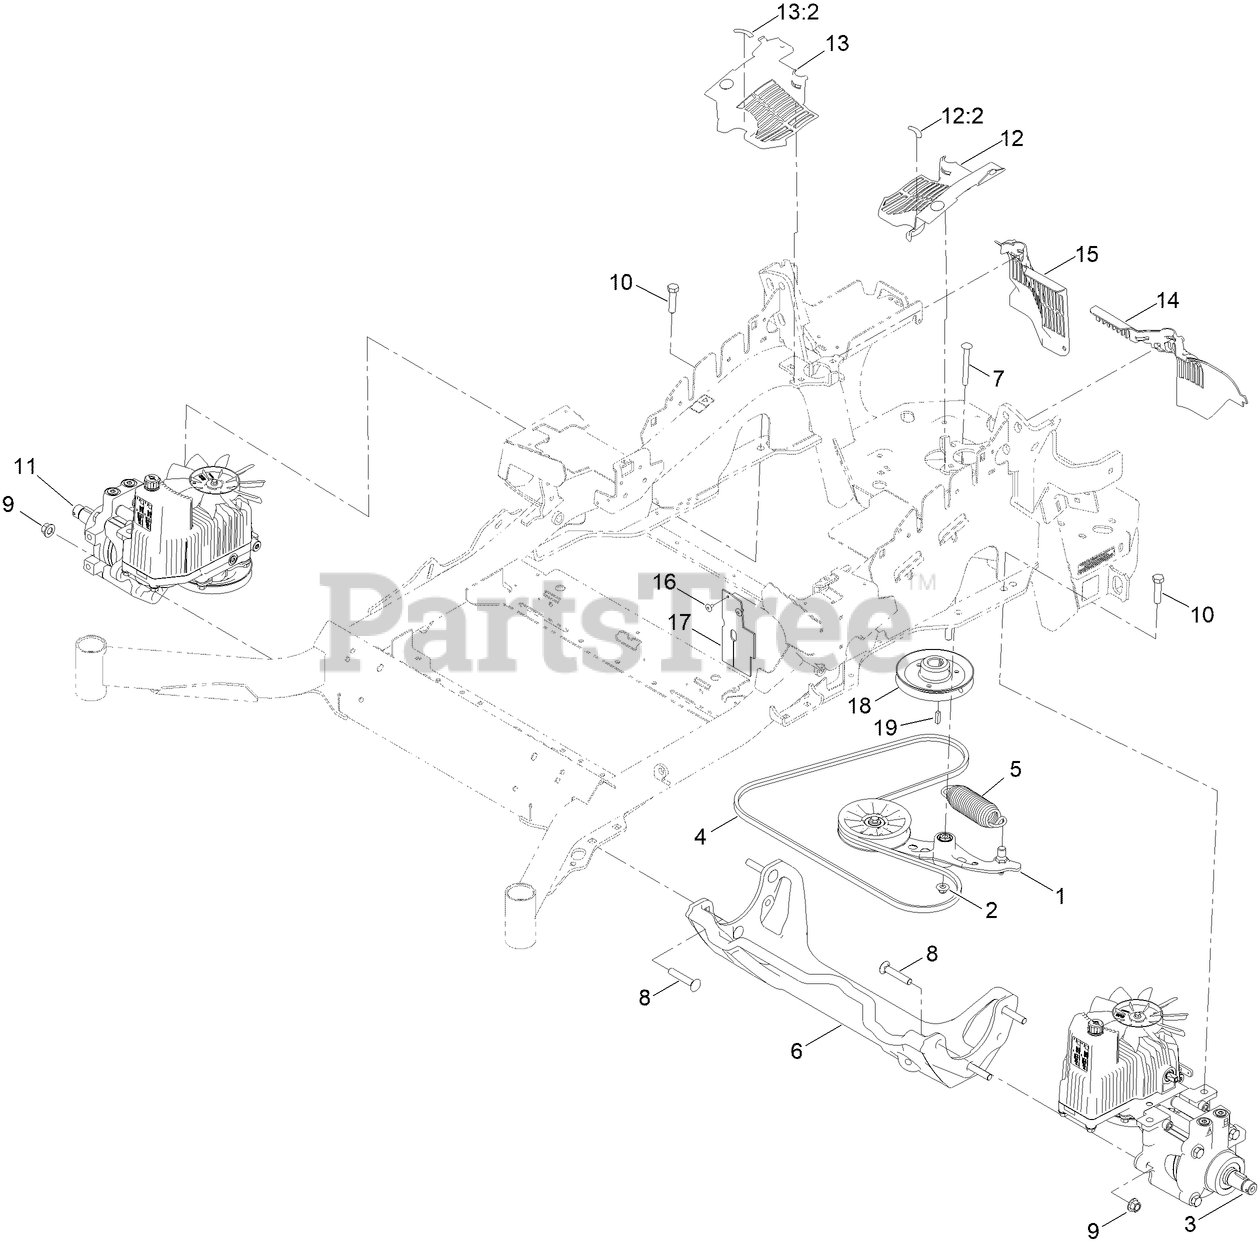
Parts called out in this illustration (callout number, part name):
1	PUMP IDLER ASM
2	NUT-FLANGE, NI
3	HYDRO-LH
4	BELT-V
5	SPRING-EXTENSION
6	CRADLE-HYDRO
7	BOLT-SHOULDER, CARRIAGE
8	SCREW-CARR
9	NUT-LOCK
10	SCREW-HH
11	HYDRO-RH
12	LH HYDRO GUARD ASM
12:2	DECAL-OIL, HYDRO
13	RH HYDRO GUARD ASM
13:2	DECAL-OIL, HYDRO
14	GUARD-HYDRO, REAR LH
15	GUARD-HYDRO, REAR (RH)
16	RIVET-POP
17	DEFLECTOR-AIR FLOW
18	SHEAVE, W/HUB
99	FILTER-HYDRO
